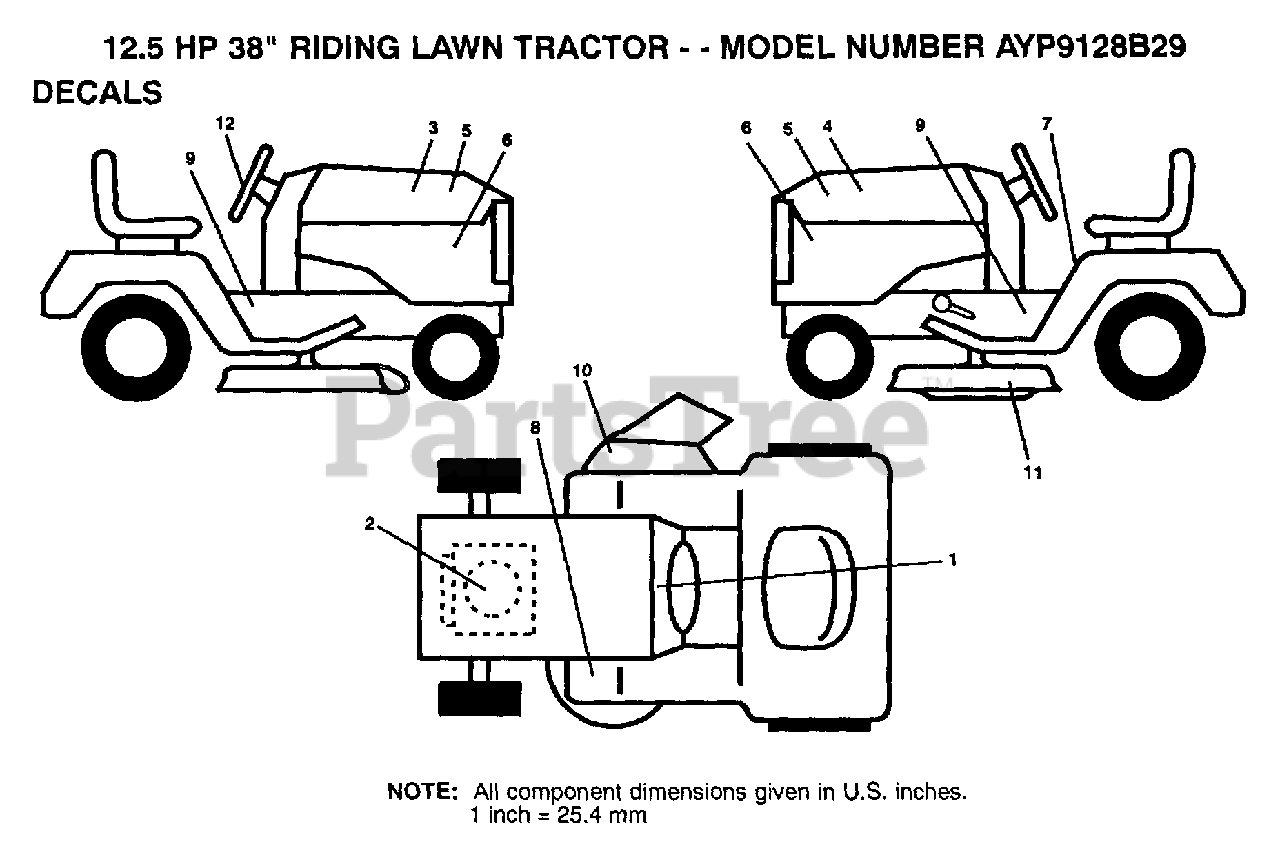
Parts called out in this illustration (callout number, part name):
7	DECAL
10	DECAL DANGER ENGLISH
11	DECAL INSTRUCTION CAUTION
